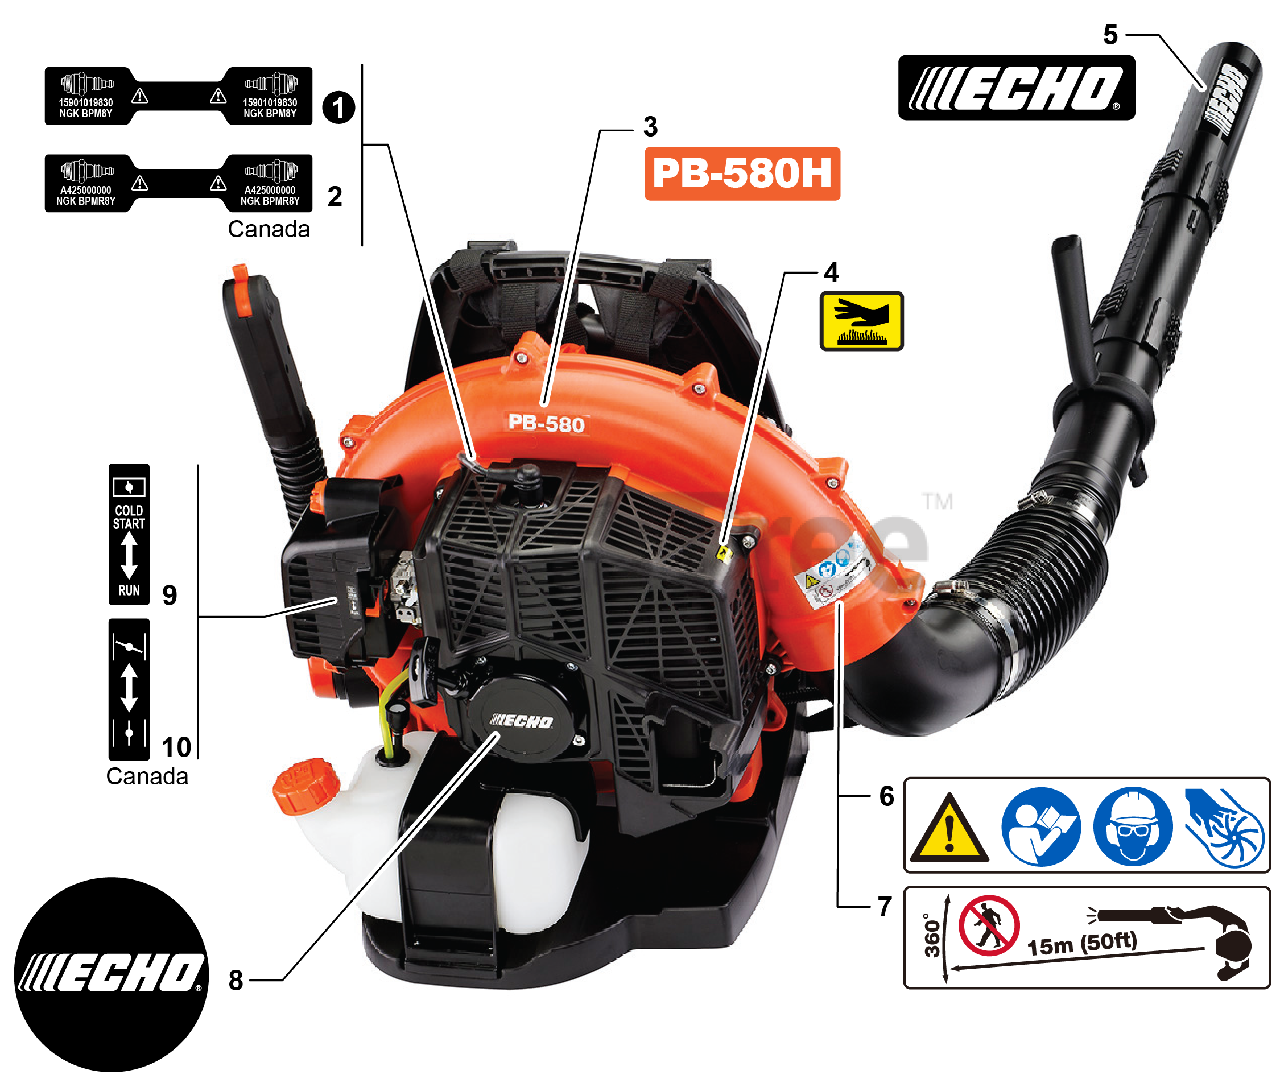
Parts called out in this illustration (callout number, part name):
1	LABEL, SPARK PLUG - BPM8Y
2	LABEL, SPARK PLUG - BPMR8Y
3	LABEL, MODEL - PB-580H
4	LABEL, CAUTION - HOT
5	LABEL, ECHO BLOWER TUBE
6	LABEL, CAUTION - ISO
7	LABEL, CAUTION - BLOWER
8	LABEL, ECHO
9	LABEL, CHOKE
10	LABEL, CHOKE
